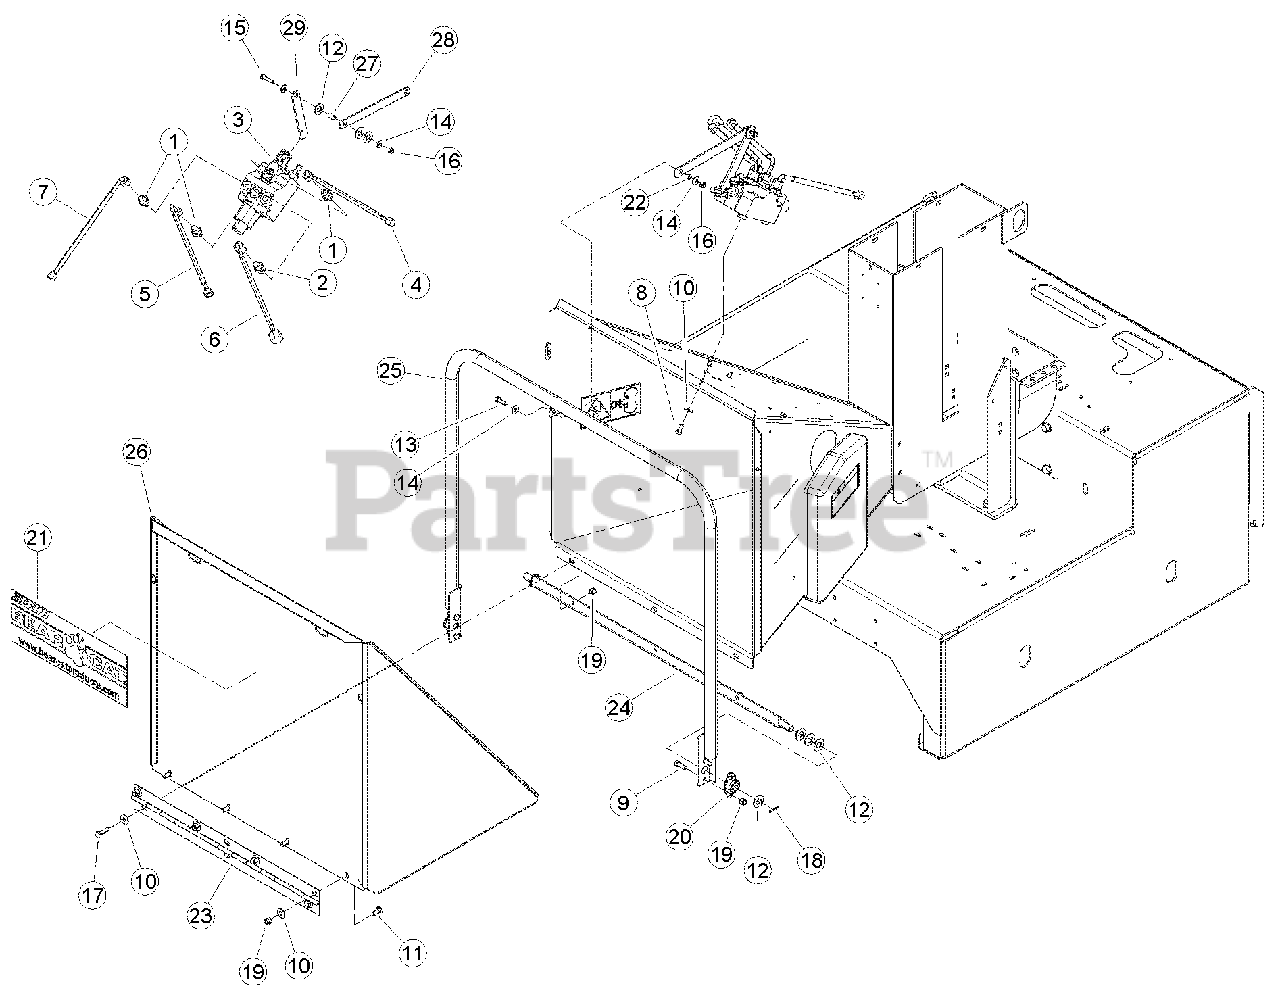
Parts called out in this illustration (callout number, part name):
1	ADAPTER, -8 MORING / -8 MJIC
2	ADAPTER, -10 MORING / -8 MJIC
3	VALVE, 4 POSITION W/DETENTS
4	HOSE ASSY, -8 FMJIC / -8 FMJICSW 90 DEG. X 37
5	HOSE ASSY, -8 FMJIC / -8 FMJICSW 90 DEG. X 35
6	HOSE ASSY, -10 FMJIC / -8 FMJICSW 90 DEG. X 53
7	HOSE ASSY, -10 FMJIC / -8 FMJICSW 90 DEG. X 82
8	BOLT, 3/8 X 3/4 HEX HD GR5 ZP
9	BOLT, 3/8 X 1 HEX HD GR5 ZP
10	WASHER, 3/8 FLAT ZP
11	BOLT, 3/8 X 1 CRG GR5 NC ZP
12	WASHER, 5/8 SAE FLAT ZP
13	BOLT, 5/16 X 1 HEX HD GR5 NC ZP
14	WASHER, 5/16 FLAT ZP
15	BOLT, 5/16 X 1-1/2 HEX HD GR5 ZP
16	NUT, 5/16 NE NYLOCK ZP
17	BOLT, 3/8 X 1-1/4 HEX HD GR5 ZP
18	PIN, 1/8 X 1.00 COTTER ZP
19	NUT, 3/8 NE NYLOCK ZP
20	BEARING, SIDE FLANGE MOUNT, 5/8"
21	DECAL, BEARCAT WEB
22	SPACER, IDLER PIVOT
23	HINGE, EXTENSION TRAY
24	WELDMENT, CONTROL PIVOT
25	WELDMENT, CONTROL ARM
26	WELDMENT, CHUTE EXTENTION TRAY
27	SPACER, .50 X .775
28	LEVER, VALVE CONTROL
29	LINK, VALVE CONTROL
